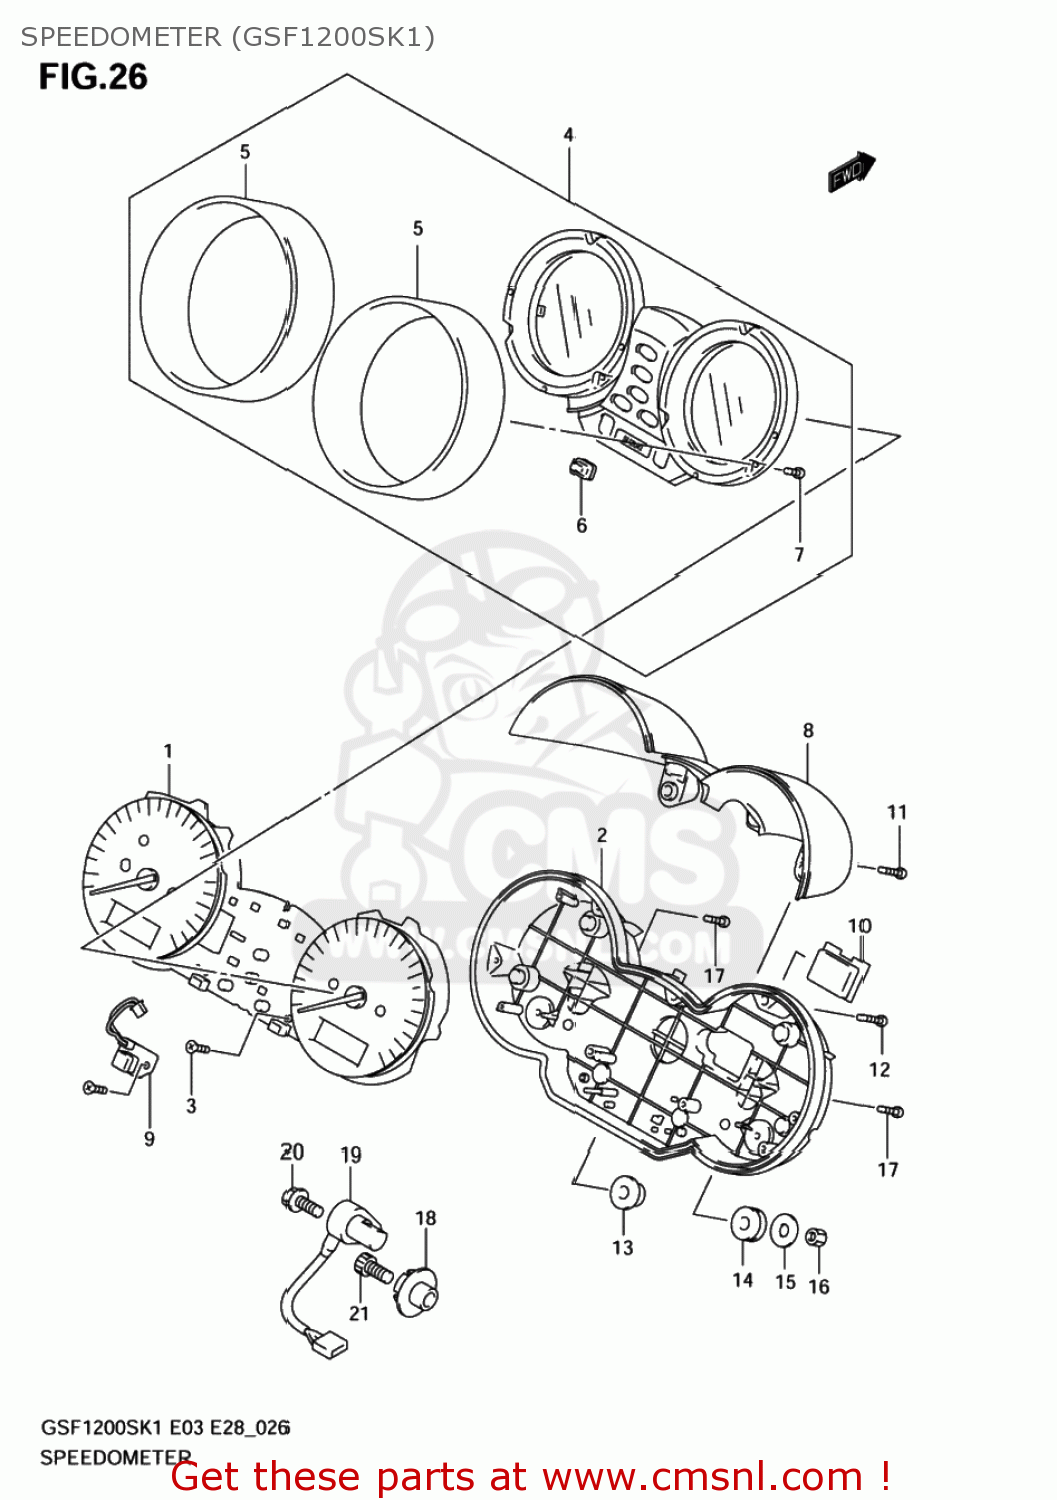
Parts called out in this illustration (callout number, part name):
1	KM TELLER
2	CASE ASSY,LWR
3	SCREW(4X14)
4	UPR CASE ASSY
5	RING
6	RUBBER,SWITCH
7	SCREW(2.3X8)
8	COVER
9	SWITCH,PRINT CIRCUIT
10	GROMMET
11	SCREW,PAN HEAD(3X14)
12	SCREW(3X16)
13	CUSHION
14	CUSHION
15	WASHER(5.5X16X1.2)
16	NUT
17	SCREW,PAN HEAD(3X16)
18	ROTOR,SPEED
19	SENSOR,SPEED
20	BOLT
21	BOLT
